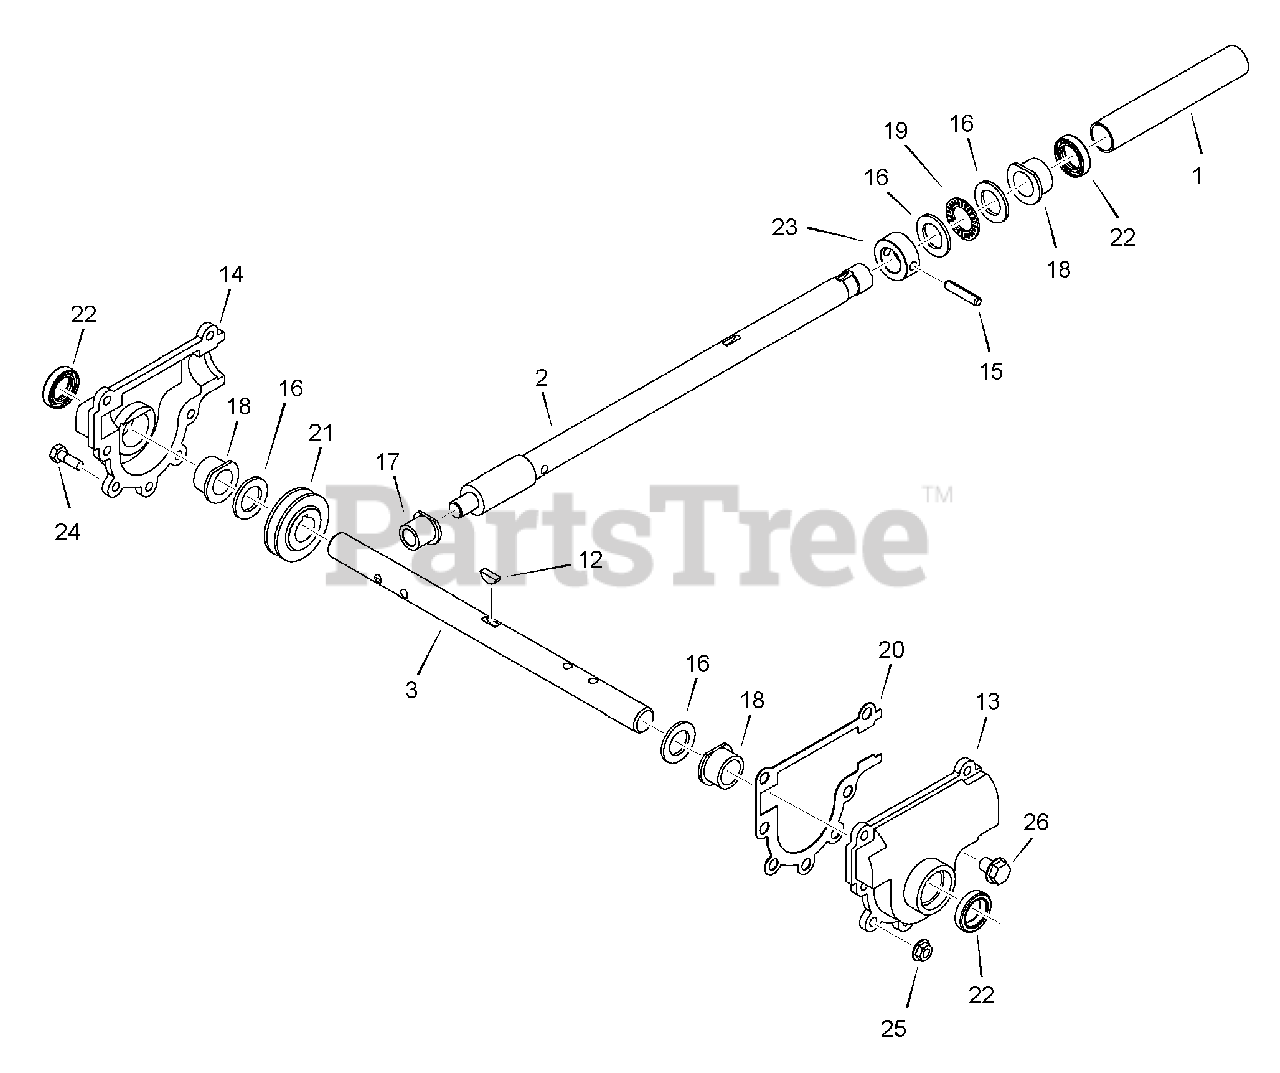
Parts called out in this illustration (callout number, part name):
1	TUBE, Plastic
2	SHAFT, Impeller
3	SHAFT, Auger Intermediate
12	KEY, Woodruff, #61, 5/8 x 3/16
13	GEAR CASE, LH
14	GEAR CASE, RH
15	PIN, Spring
16	WASHER, Thrust
17	BUSHING, Worm
18	BUSHING, Shaft
19	BEARING, Needle Thrust
21	GEAR, Worm
22	SEAL, Oil
23	COLLAR, Thrust, 3/4 X 1-1/4
24	CAPSCREW, 1/4-20 X 3/4
25	NUT, Hex-Flange, Center-Lock, 1/4-20
26	SCREW, 3/8-16 X 1/2
